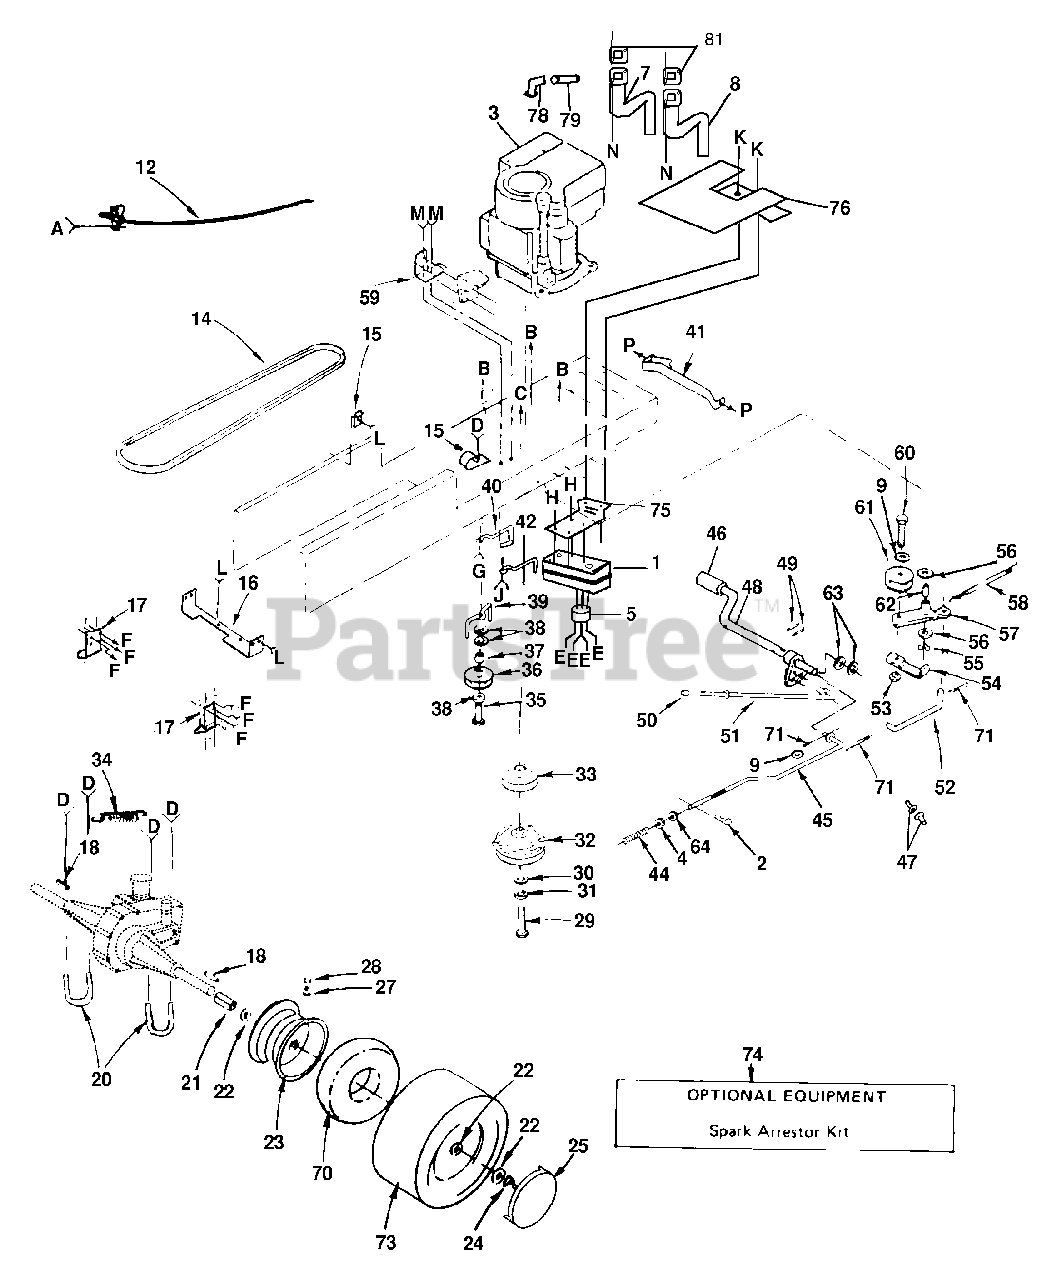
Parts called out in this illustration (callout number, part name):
2	Clip, Hairpin
3	Engine, 16 HP Vanguard Model #303777 Type 0015-02
4	Nut, Hex, Jam 3/8 x 16 UNC
5	Deflector
7	Tube Manifold, L.H.
8	Tube Manifold, R.H.
9	Washer 13/32 x 13/16 x 16 Gauge
12	Control, Throttle/Choke
14	V-Belt, Drive
15	Clip
16	Bracket, Mounting, Hydro T/A
17	Bracket, Transaxle
18	Key, Square 1/4 x 2
20	U-Bolt 3/8-16 x 2.83
21	Spacer, Split
22	Washer 1-1/32 x 1-5/8 x 16 Gauge
23	Rim, Rear
25	Cover, Wheel
27	Stem, Valve
28	Cap, Valve
29	Bolt, Hex, Fin 7/16-20 UNF x 4 Grade 8
30	Washer 1-1/2 OD x 15/32 ID x .250
31	Washer, Lock 7/16
32	Clutch, Electric
33	Pulley, Engine
34	Spring, Brake Return
35	Bolt, Hex 3/8-16 x 2-3/4
36	Idler, Flat
37	Spacer
38	Washer 13/32 x 13/16 x 12 Gauge
39	Retainer, Belt
40	Keeper, Belt, Engine, L.H.
41	Retainer, Clutch Assembly
42	Belt, Keeper, Engine, R.H.
44	Spring, Rod, Brake
45	Rod, Brake
46	Cover, Pedal
47	Bearing, Nylon
48	Shaft, Foot Pedal, Assembly
49	Pin, Roll 3/16 x 1
50	Cap, Plunger
51	Rod, Brake, Park
52	Link, Clutch
53	Nut, Crownlock 3/8-16
54	Retainer, Belt
55	Ring, Klip
56	Washer, Hardened
57	Arm, Assembly, Idler
58	Spring, Return, Clutch
59	Bracket, Switch
60	Bolt, Hex 3/8-16 x 1-1/2
61	Pulley, Idler
63	Washer 21/32 x 1 x 16 Gauge
64	Nut
70	Tube
71	Pin, Cotter 1/8 x 3/4
73	Tire
74	Spark, Arrestor Kit
75	Bracket, Muffler Mounting
76	Shield, Heat
78	Elbow, STD 90° 3/8-18 NPT
79	Nipple, Pipe
81	Gasket
